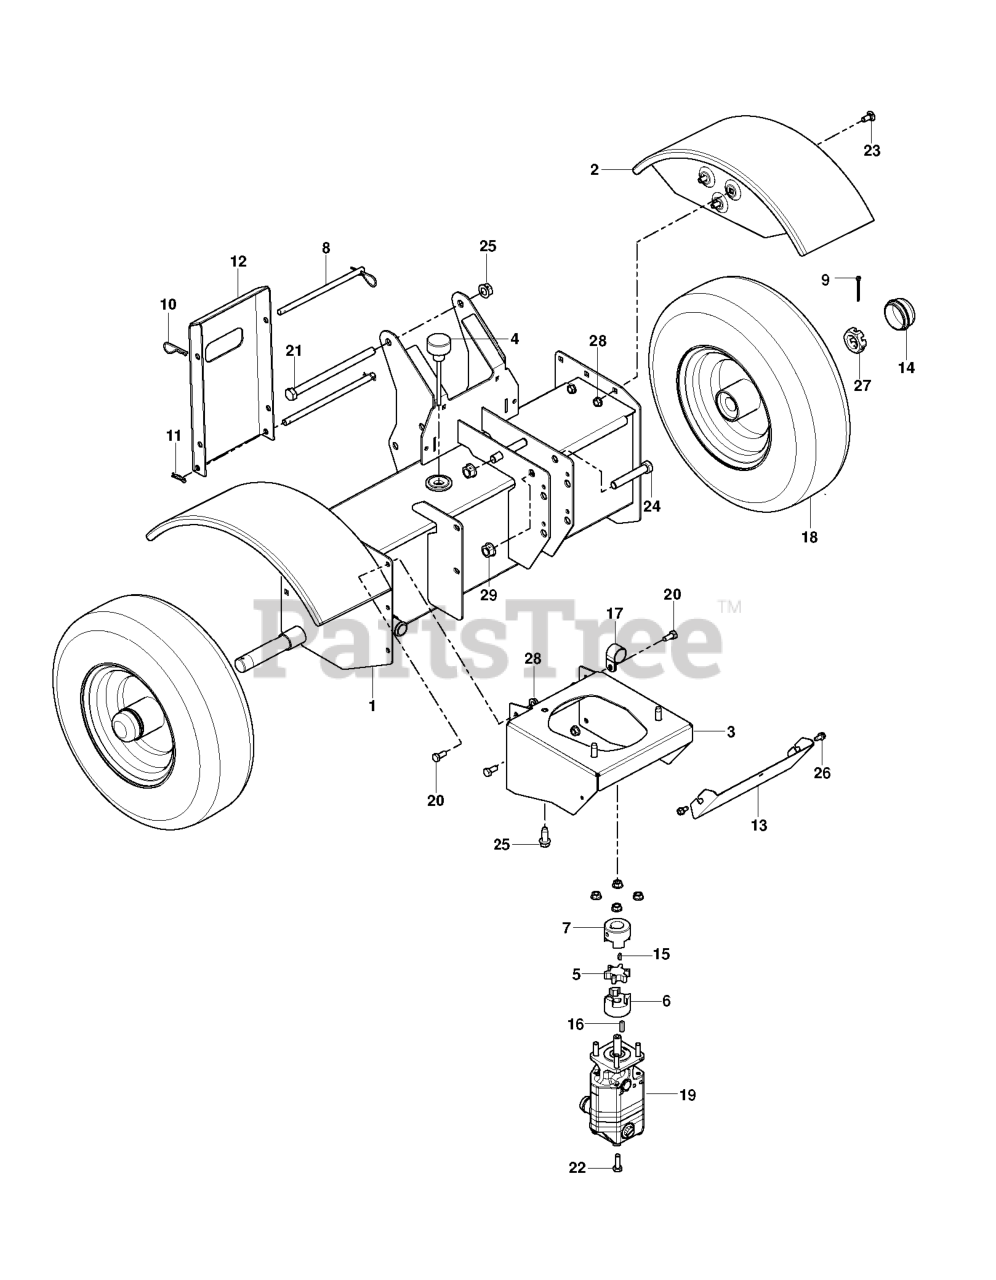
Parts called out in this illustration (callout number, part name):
1	CHASSIS, SMALL
2	FENDER CURVED
3	MOUNT MOUNT ENGINE
4	DIPSTICK DPSTK-BREATHER, STEEL
5	PAD SPIDER, URATHANE
6	COUPLER COUPLER - DRIVE 1/2"
7	COUPLER COUPLER - DRIVE, 7/8"
8	PIN PIN, .373 X 7.30 X 2X.109
9	PIN PIN, CTR .15 X 1.50 YWZC
10	PIN HAIRPIN, #7 CLIP .094X2.31
11	PIN PIN-HAIR, ENDRIES #25 YWZC
12	SUPPORT SUPPORT, REAR LEG
13	COVER COVER, COUPLING
14	CAP CAP, DUST
15	KEY KEY-WDRF .125X.50X.20 (HRD
16	KEY KEY-SQ .188X.75X.188
17	CLAMP CLAMP, COUSHIONED STEEL
18	WHEEL ASSY ASSY, TIRE/WHEEL 4.
19	PUMP, SPLITTER-11 GPM
20	BOLT BOLT HEX .31-18 X .75 GR5
21	BOLT BOLT HEX .50-13 X 7.50 GR
22	BOLT BOLT HEX .31-18 X 1.00 GR
23	BOLT BOLT RDHDSQNK .31-18X.75
24	BOLT BOLT HEX .50-13 X 3.00 GR
25	SCREW SCREW, TAP .38-16 X 1.00
27	NUT NUT, SL 1.0-14
28	NUT NUT, LK-TOP-FLG .31-18 YWZ
